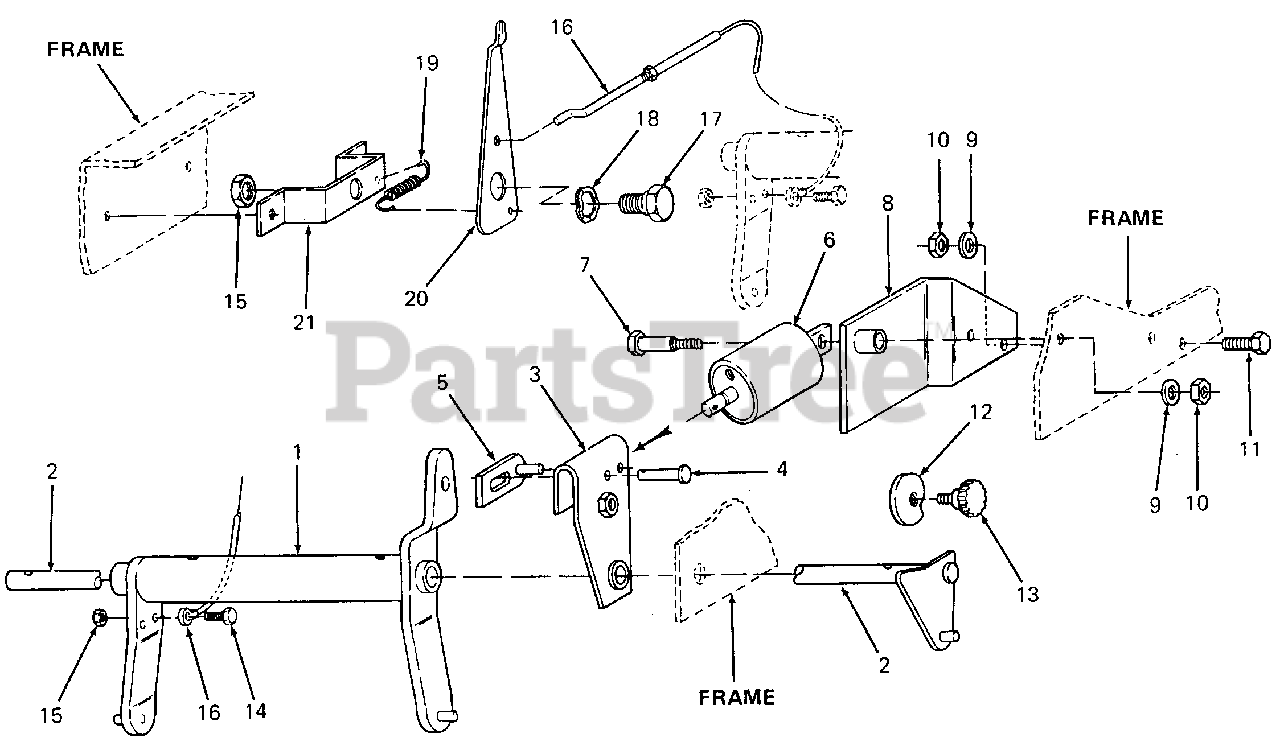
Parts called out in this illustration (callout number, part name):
1	Lift Assy, Rockshaft
4	Pin, Clevis, 1/2 Dia X 2.172 Lg
5	Pin Assy, Lift
6	Cylinder, Hydraulic
7	Bolt, Shoulder
8	Bracket, Cylinder
9	Washer, Flat, .531 X 1.06 X .134 Thk
10	Nut, Hex Center Lock, 1/2-13 GR5
11	Screw, Hex Cap, 1/2-13 X 1.25 Lg GR5
14	Screw, Hex Cap, 1/4-20 X .88 Lg
15	Nut, Hex Patch Lock, 1/4-20
16	Cable Assy, Indicator
17	Screw, Shoulder, .375 Dia X .181
18	Washer, Bowed Spring
19	Spring, Extension, .33 OD X 1.12 Lg
20	Indicator Arm
21	Bracket, Mounting
